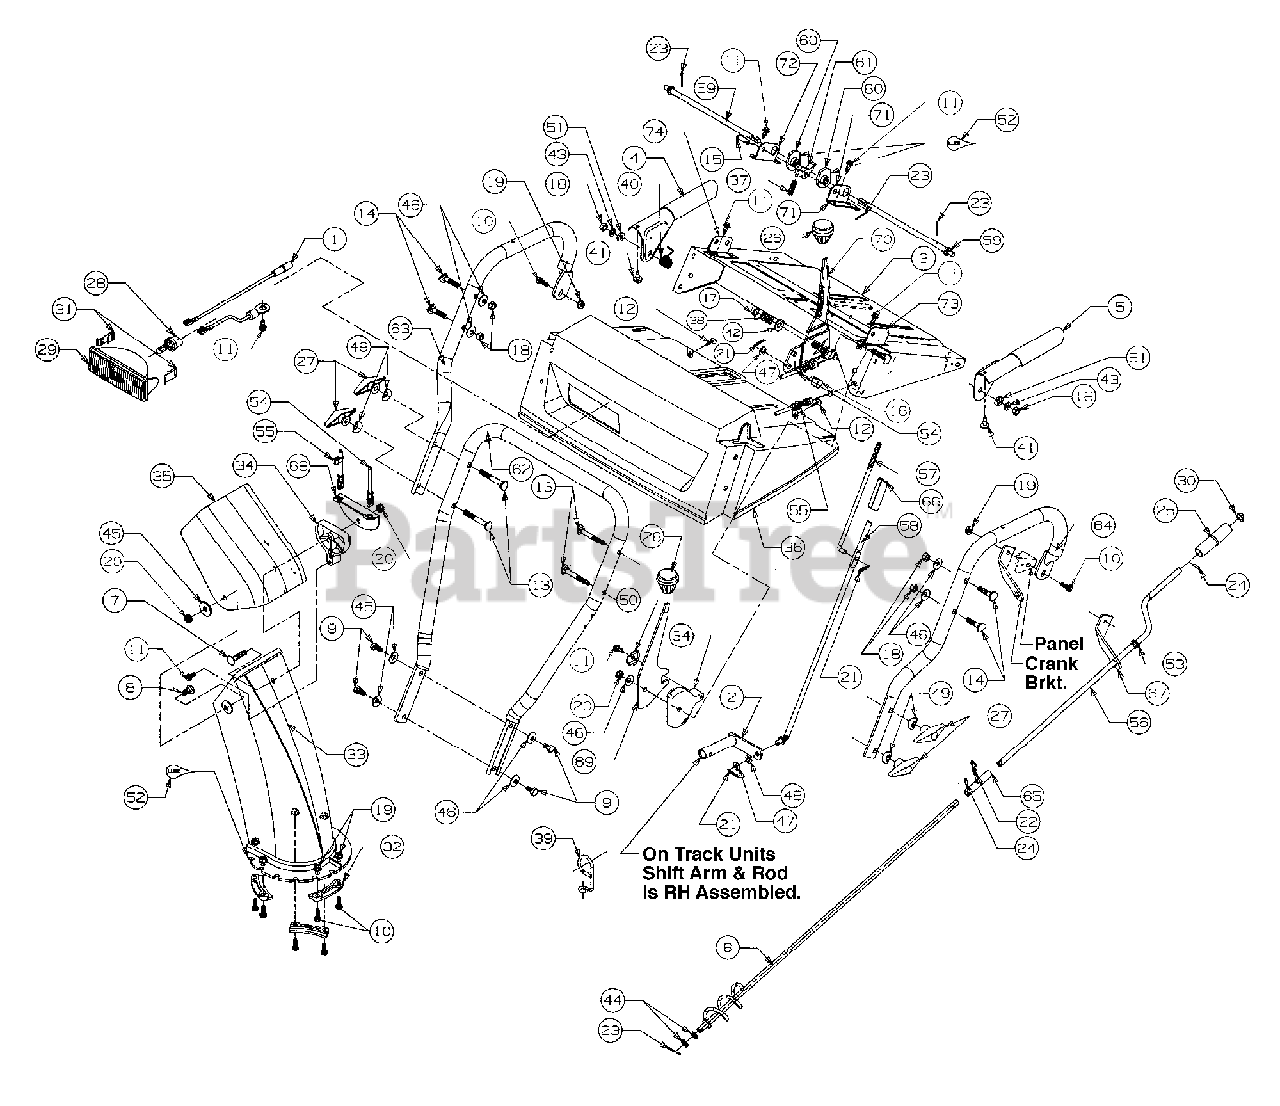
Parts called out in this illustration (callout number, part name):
1	Harness-Light
5	Handle - Engagement - L.H.
8	Bolt - Carriage
9	Screw - Hex
10	Screw - Hex
11	Screw - Washer Head-Hex
12	Screw - Hex
13	Bolt - Carriage
14	Bolt - Carriage
15	Pin - Clevis
16	Ferrule
17	Nut - Hex Lock
18	Nut - Hex
19	Nut - Hex Lock
20	Nut - Hex Lock
21	Pin - Cotter Internal
22	Pin - Cotter
23	Pin - Cotter
24	Pin - Roll
25	Knob - Chute Crank
26	Knob - Shift
27	Knob - Wing Nut
28	Lamp
29	Housing - Lamp
30	Cap - Push
31	Clip - Retaining
32	Keeper - Chute
33	Chute - Lower
34	Guide - Cable
35	Chute - Upper
36	Panel - Handle
37	Spring
38	Spring
39	Wire - Control
40	Spring
41	Bumper
42	Washer - Bell
43	Washer - Lock
44	Washer - Flat
45	Washer
46	Washer - Bell
47	Washer - Flat
48	Washer - Lock
49	Washer - Saddle
50	Washer
51	Washer
52	Lubricant
53	Bushing - Plastic
54	Cable - Chute Control
55	Cable - Chute Control
56	Crank - Chute
57	Rod - Shift Upper
58	Rod - Shift Lower
59	Rod - Cam
60	Cam - Handle Lock
61	Pawl - Handle Lock
66	Connector
70	Handle - Shift
